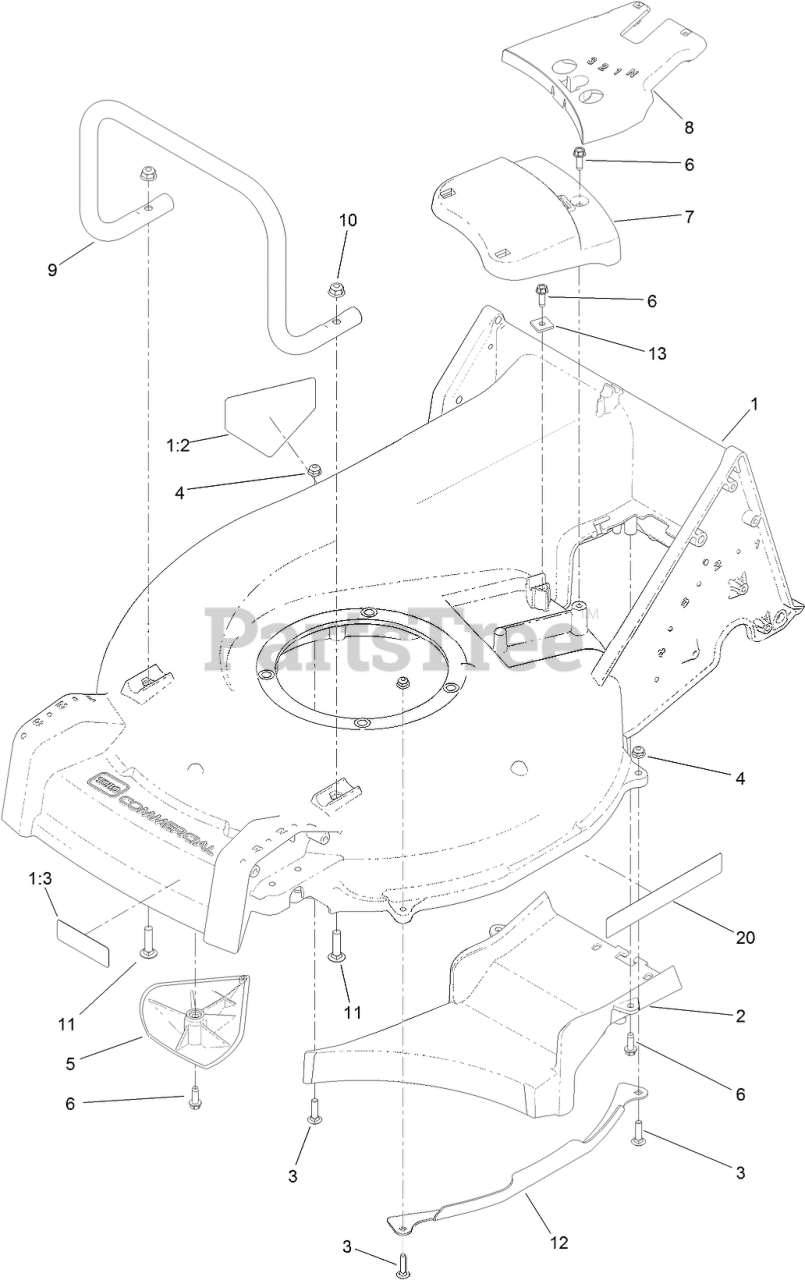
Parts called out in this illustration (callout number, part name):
1	HOUSING ASM
1:2	DECAL-DANGER
1:3	DECAL-WARNING, BLADE
2	FLOOR-CHUTE
3	SCREW-CARR
4	NUT-HF
5	KICKER
6	SCREW-HWHTF
7	COVER-BELT, FRONT
8	COVER-BELT, REAR
9	GUARD-ENGINE
10	NUT-HF, NI
11	SCREW-CARR
12	GUARD-SIDE, DECK
13	CLAMP-CABLE
20	DECAL-RECYCLER
